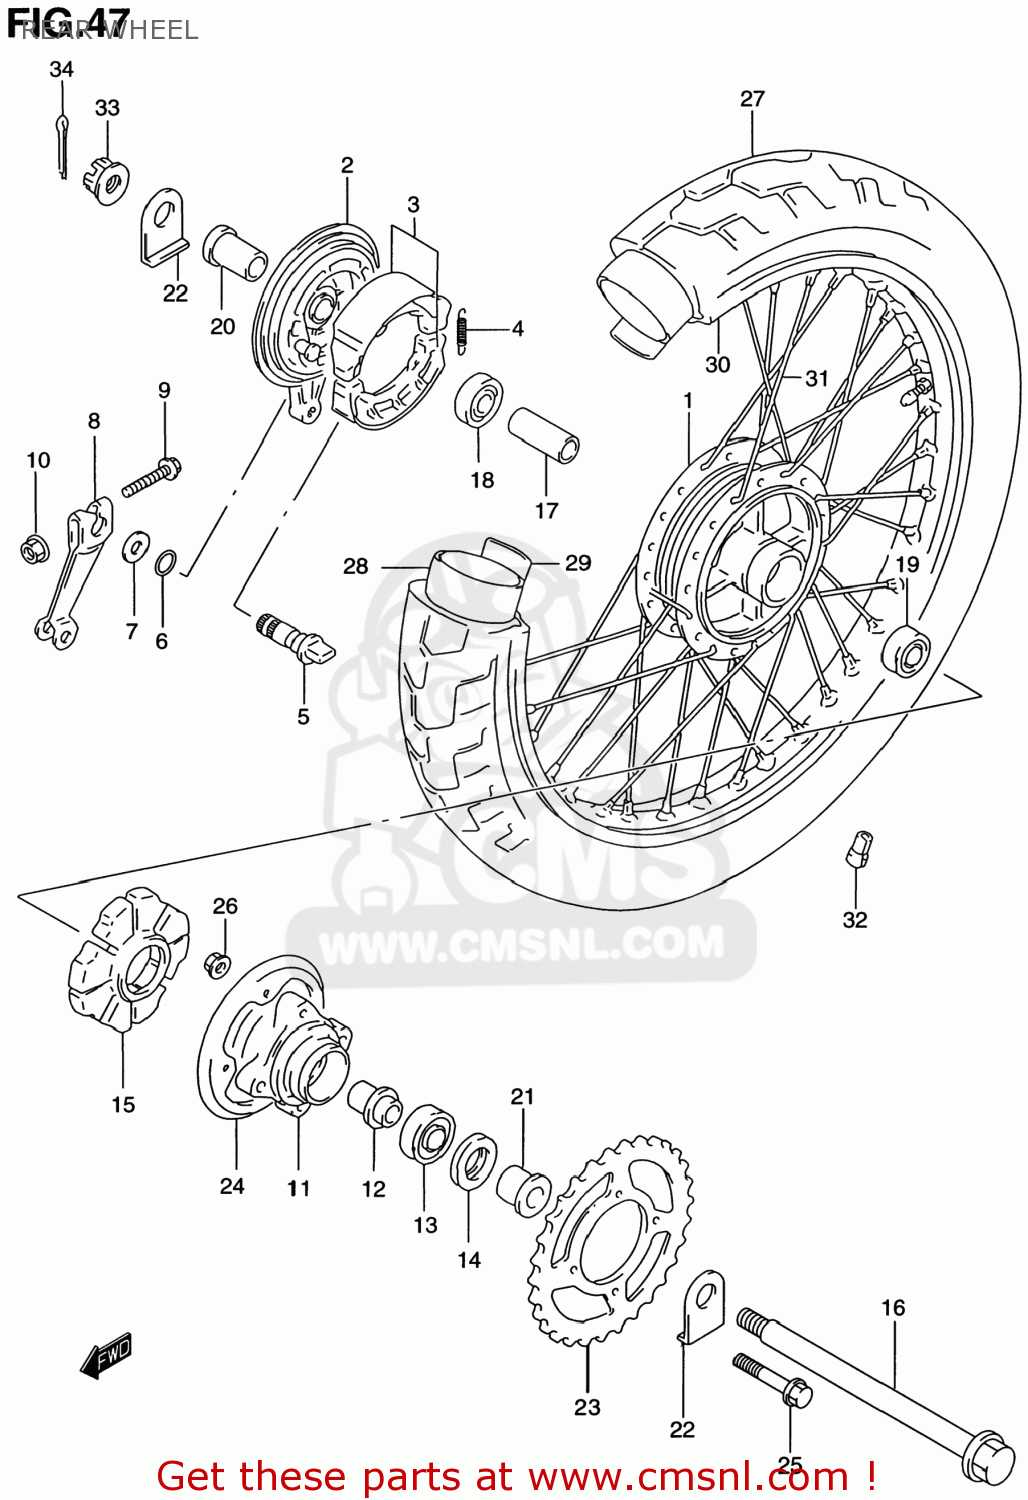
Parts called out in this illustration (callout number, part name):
1	HUB,RR WHEEL
2	PANEL,RR BRAKE ANCHOR
3	SHOE SET,BRAKE (NAS)
4	SPRING(L:34)
5	CAM,BRAKE
6	O RING(D:2.5,ID:13.8)
7	WASHER(14.5X22X1.6)
8	LEVER,RR BRAKE CAM
9	BOLT
10	NUT
11	DRUM,RR SPROCKET MOUNTING
12	RETAINER,RR SPROCKET DRUM
13	BEARING(20X47X14)
14	SEAL,OIL(28X47X7)
15	ABSORBER ASSY,HUB SHOCK
16	AXLE,RR
17	SPACER(15.3X21.7X63)
18	BEARING
19	BEARING
20	SPACER,RR AXLE,R
21	SPACER,RR AXLE,L
22	WASHER,CHAIN ADJUSTER GUIDE
23	SPROCKET,RR(NT:41-520)
24	GUIDE,RR SPROCKET CHAIN
25	BOLT(10X40)
26	NUT
27	TIRE,RR(130/90-15)
28	TUBE ASSY,WHEEL INNER
29	PROTECTOR,WHL INR TUBE
30	RIM,RR WHEEL(15XMT3.00)
31	SPOKE SET,RR WHEEL
32	BALANCER,WHEEL (B)
33	NUT
34	COTTER PIN
